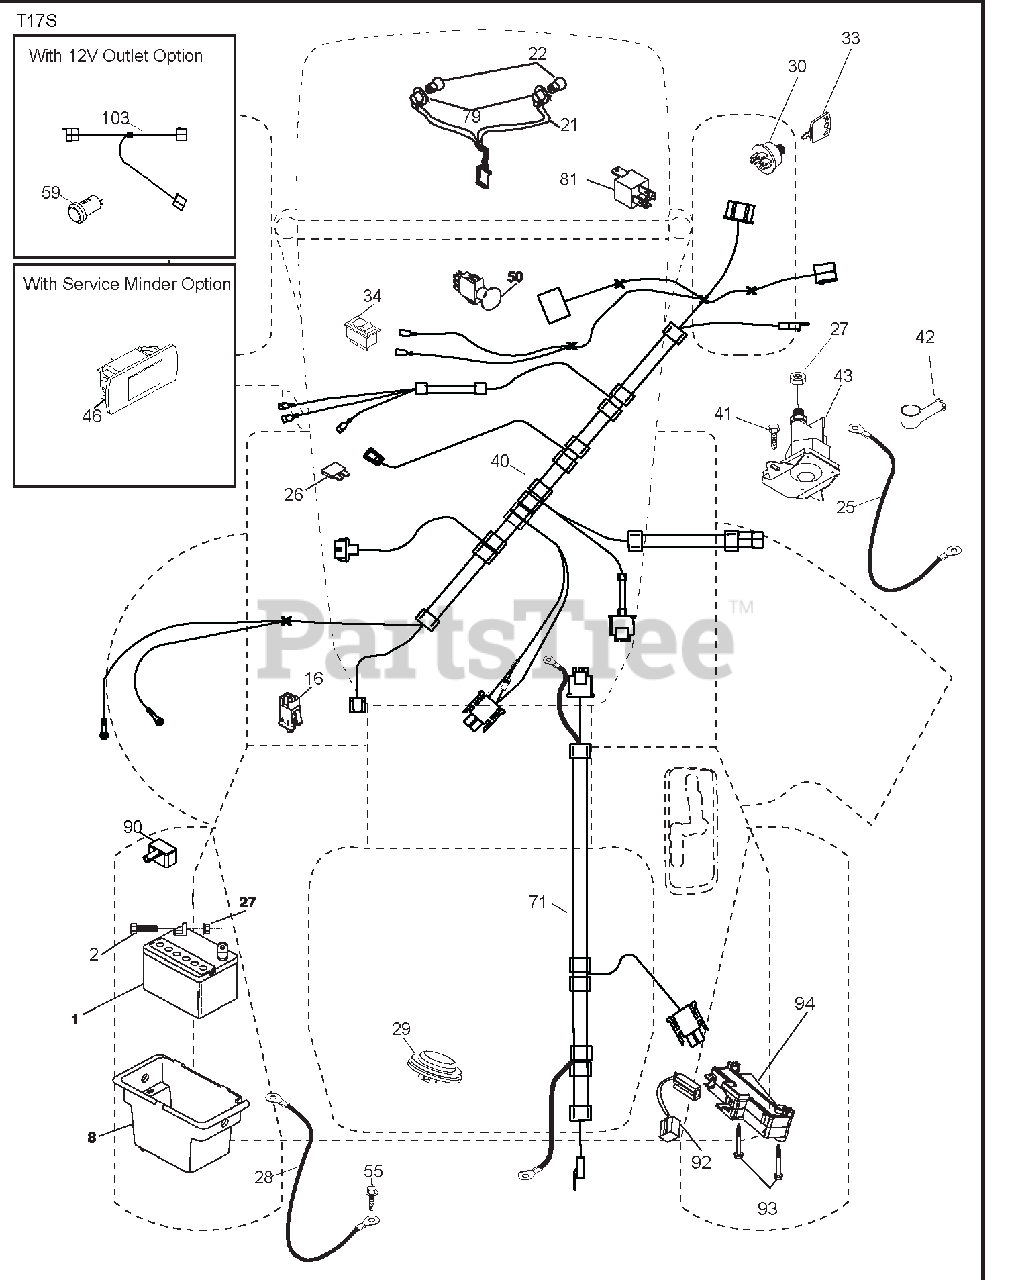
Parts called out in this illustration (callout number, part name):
1	BATTERY.12.VOLT.28.AMP.WET
2	BOLT.HEX.HD.1/4-20UNC X 3/4
8	BOX.BATTERY.MNT.REAR.LT.TEX.BL
16	SWITCH.INTERLOCK.NONO.GRAY
21	HARNESS ASM.LIGHT.22"(4152J)
22	BULB.LIGHT.#1156
25	CABLE.STARTER
26	FUSE.20 AMP.
27	Nut, Keps Hex 1/4-20 unc
28	CABLE.BLACK.22"REAR BATT.TEX
29	SWITCH.SEAT.DELTA.OPC.9LB.
30	SWITCH.IGN.DLTA.P-IN.ROS
33	KEY/CHAIN.BLISTER PACK.GEN.USA
34	SWITCH.LIGHT/RESET.B/B/RED.
40	HARNESS IGN ELEC RELAY
41	Screw 1/4-20 x 1/2
42	COVER.TERMINAL.RED
43	SOLENOID.W/BRASS PLUNGER.2005
46	HOUR METER
50	SWITCH.PTO.8 TERMINAL.BLACK
55	SCREW.5/16-18X3/4.SMGML.TAP/R
71	HARNESS.IGN.CHASS.TEX.REAR.BAT
79	SOCKET ASM.BULB.TWISTLOCK
81	RELAY HARNESS SEALED
90	COVER TERMINAL BATTERY FR. TEX
92	HARNESS.PIGTAIL.CONSLE.ROS.MLK
93	SCREW.PLASTITE.10-14 X 2.0
94	MODUAL REVERSE ROS
